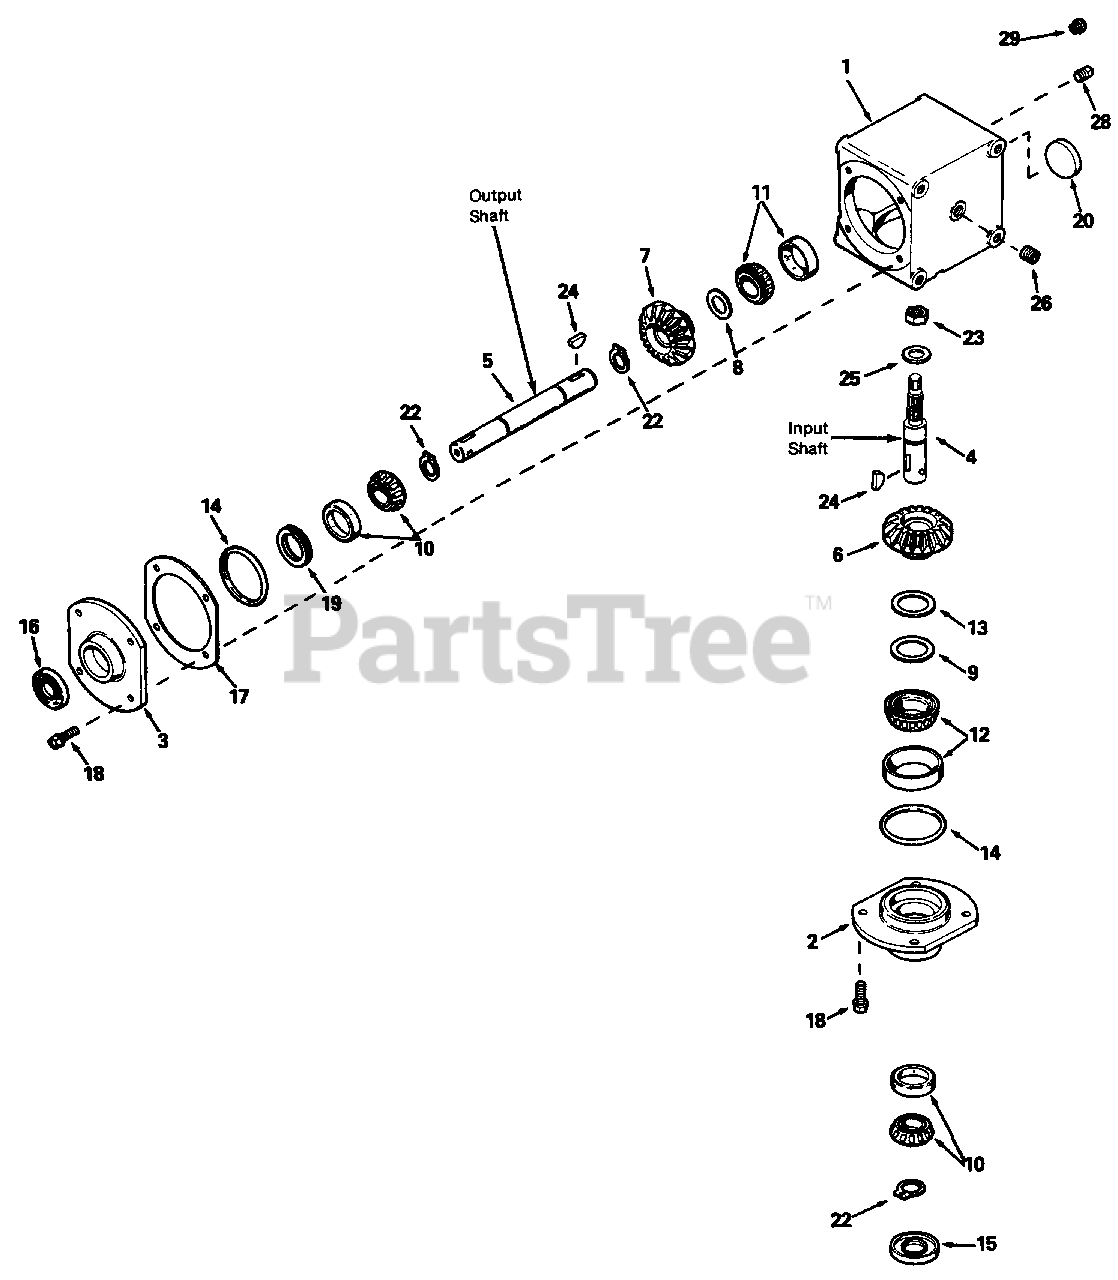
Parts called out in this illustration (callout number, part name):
1	HOUSING, Right Angle Drive
2	CAP, Retainer
3	CAP, Retainer
4	SHAFT, Input
5	SHAFT, Output
6	GEAR, Bevel
7	GEAR, Bevel
8	SHIM (1-1/2" O.D. x 1-1/64" I.D. x .002 thick)
9	SHIM (1-3/4" O.D. x 1.265" I.D. x .002 thick)
10	BEARING & CUP ASSY.
11	* BEARING & CUP ASSY.
12	BEARING & CUP ASSY.
13	RACE, Thrust
15	SEAL, Oil
16	SEAL, Oil
17	SHIM, Cap Retainer
18	SCREW, Hex Hd. Sems, 5/16-18 x 1
19	RING, Load
22	RING, Retaining
23	JAM NUT, 1/2-20, Hex
24	KEY, Woodruff
25	WASHER, Flat
26	PLUG, Pipe, 1/4-18
28	PLUG, Pipe, 1/8"
29	VALVE, Relief
